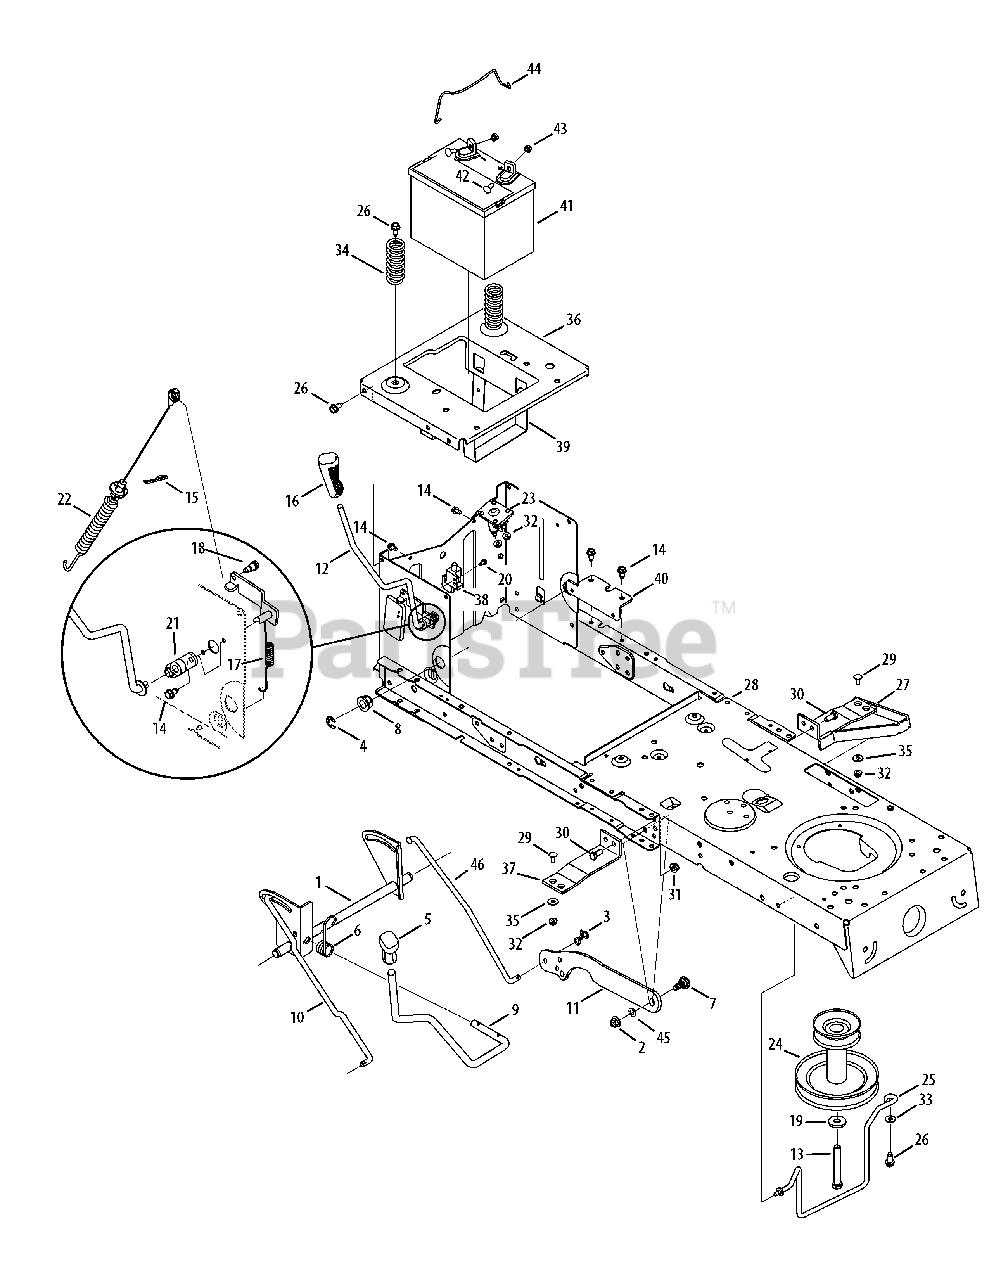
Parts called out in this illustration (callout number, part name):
1	Lift Assembly
2	Nut, Hex Flange Insert Lock, 3/8-16
3	Bow-Tie Pin, 91, RH
4	E-ring, .625 Shaft
5	Grip, Handle
6	Torsion Spring
7	Shoulder Bolt, 3/8-16 x .50 x .270
8	Bearing, Hex Flange,
9	Deck Lift Handle
10	Lift Rod, RH
12	PTO Handle Assembly
13	Screw, Hx. Hd., 7/16-20 x 3.25
14	Screw, Hd. Tapp, 1/4-20 x .5
15	Click Pin
16	Handle Grip
17	PTO Spring, Extension
18	Shoulder Bolt, 1/4-28 x .342 x .335
19	Washer, Flat, .450 x .250 x .164
20	Shoulder Screw, #10-32 x .500
21	PTO Bearing
22	Deck Engagement Cable
23	12v. Solenoid
24	Engagement Pulley
25	Belt Keeper Rod Assembly
26	Screw, Hd. Tapp, 5/16-18 x .75
27	Support Bracket Assembly
28	Rider Frame Assembly
29	Carriage Screw, 1/4-20 x .62
30	Screw, Hx. Hd., 5/16-18 x .75
31	Nut, Hex Flange Insert Lock, 5/16-18
32	Nut, Hex Flange Insert Lock, 1/4-20
33	Flat Washer, .406 x .875 x .059
34	Spring, Compress., 1.28 x 3.125
35	Flat Washer, .28 x .74 x .063
36	Seat Bracket Frame
37	Running Board Bracket
38	Interlock Switch
39	Battery Bracket
40	Frame Brace Bracket
41	Battery
42	Screw, Shoulder, .250 x .150
43	Nut, Sems, 1/4-20
44	Battery Rod
45	Flat Washer, .385 x .62 x .063
46	Lift Rod, LH
